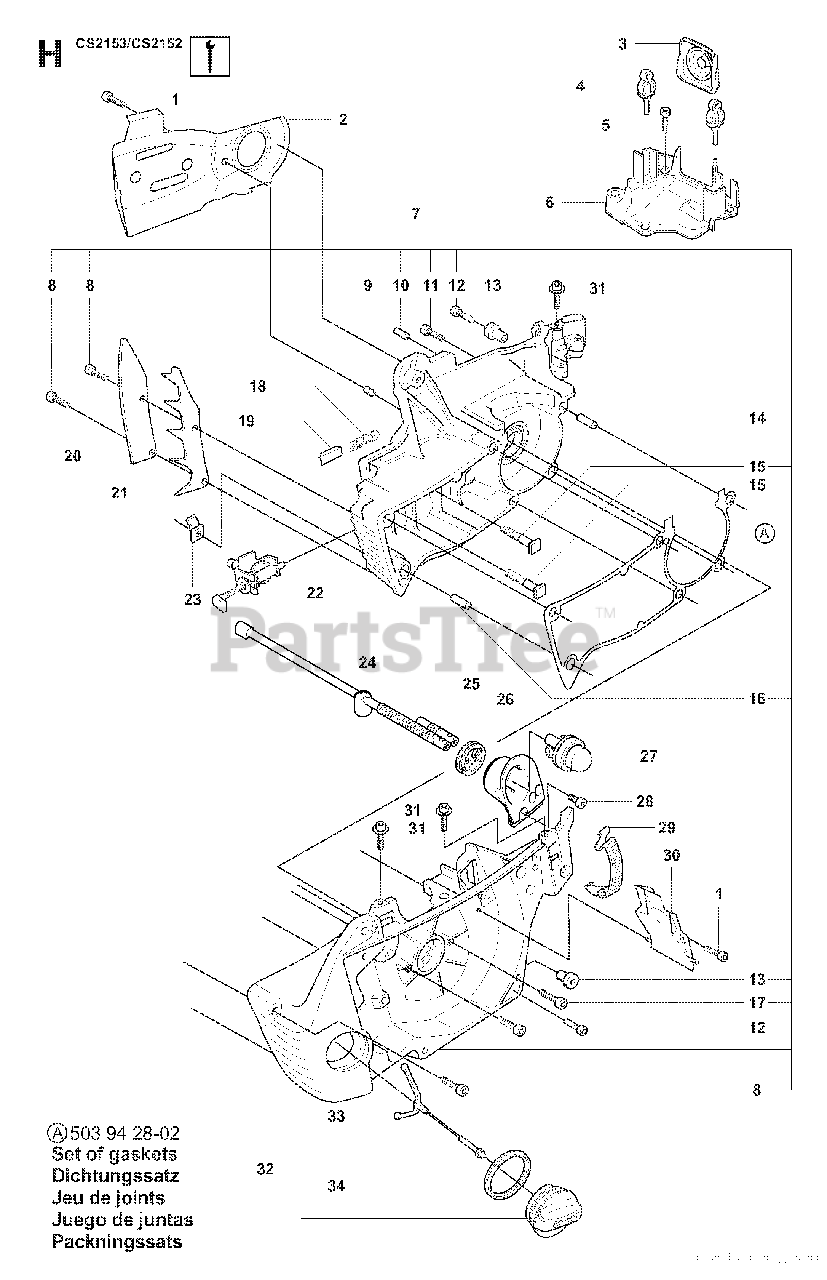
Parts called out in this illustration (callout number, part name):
2	CHAIN GUIDE PLATE
4	SUPPORT
6	CARBURETTOR AREA BASE
7	CRANKCASE ASSY
13	MOVEMENT LIMITER
18	LOCK SPRING
21	FELLING DOG
22	CHAIN TENSIONER
23	CHAIN CATCHER
24	RP HOSE
27	AIR PURGE BUBBLE
28	SCREW IHSCT
30	DEFLECTOR
34	OILCAP GASKET
A	GASKET SET
